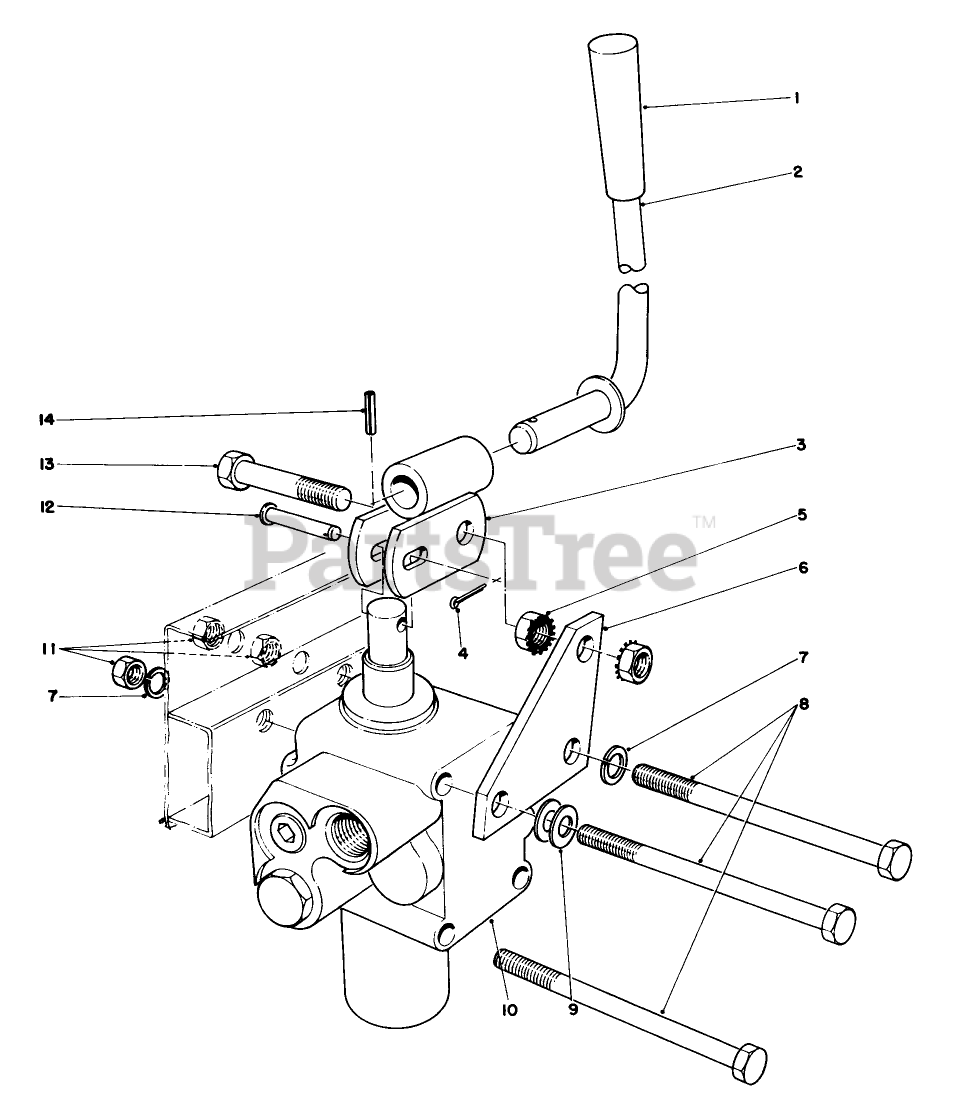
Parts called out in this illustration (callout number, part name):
1	KNOB-CONTROL
2	Lever-Valve
3	Valve Lever Link
4	PIN-COTTER
5	NUT-KEPS
6	Wheel Bolt
7	WASHER-LOCK
8	SCREW-HH
9	WASHER-FLAT
10	VALVE ASM
11	NUT-HEX
12	PIN-CLEVIS
13	SCREW-HH
14	PIN-ROLL
